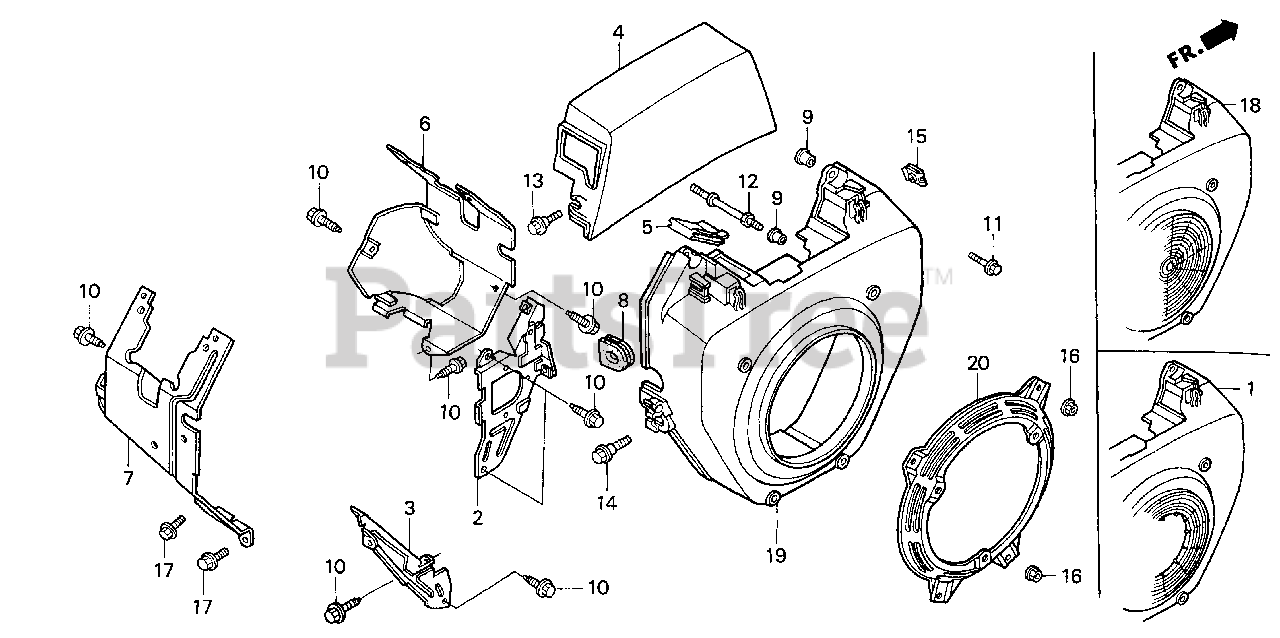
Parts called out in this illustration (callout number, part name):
2	PLATE, R. SIDE
3	PLATE, L. SIDE
4	HOOD, FAN COVER
6	SHROUD, R.
7	SHROUD, L.
8	GROMMET, WIRE
9	COLLAR B, TAILLIGHT
10	BOLT, FLANGE (6X12) (CT200)
11	BOLT, FLANGE (6X23)
12	BOLT, STUD (6X75)
13	BOLT, FLANGE (6X20)
14	BOLT, FLANGE (6MM) (BLACK)
15	NUT, SPRING (6MM)
16	NUT, FLANGE (6MM)
17	BOLT, FLANGE (6X8)
19	COVER, FAN *R8* (RECOIL STARTER) (BRIGHT RED)
20	SPACER, RECOIL STARTER MOUNTING *R8* (BRIGHT RED)
